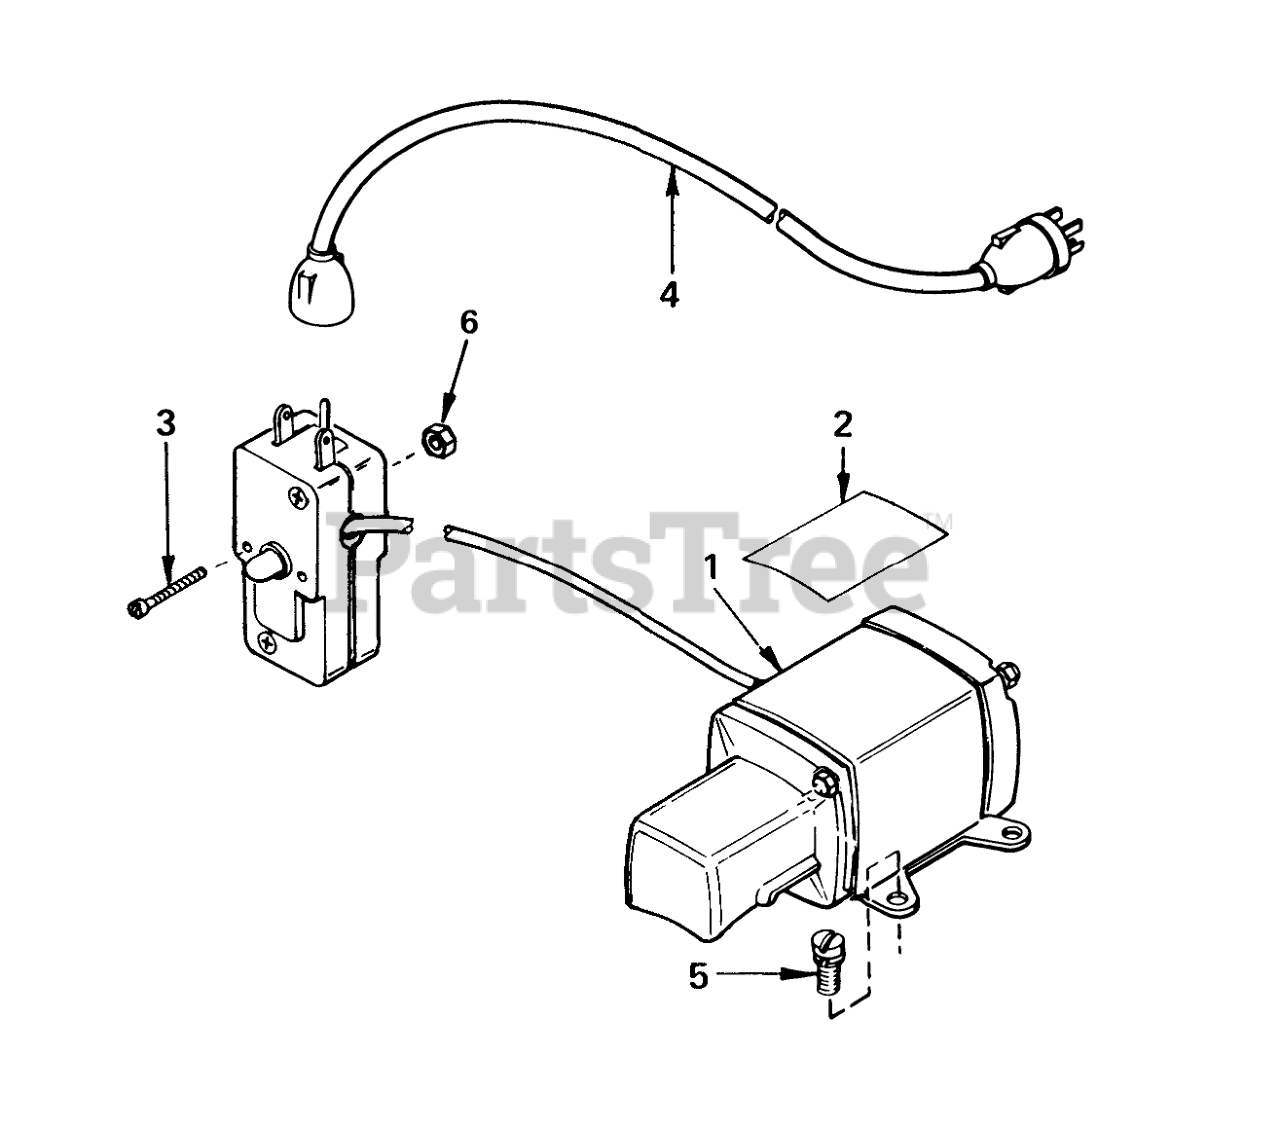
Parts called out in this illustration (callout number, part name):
1	Motor-Cranking (CSA Approved (Incl. Ref. #2 thru 6)
2	Decal
3	Screw, Pan Hd.
4	Cord-Extension
5	Screw (T-30, 1/4-20 x 23/32)
6	Nut & Lockwasher
